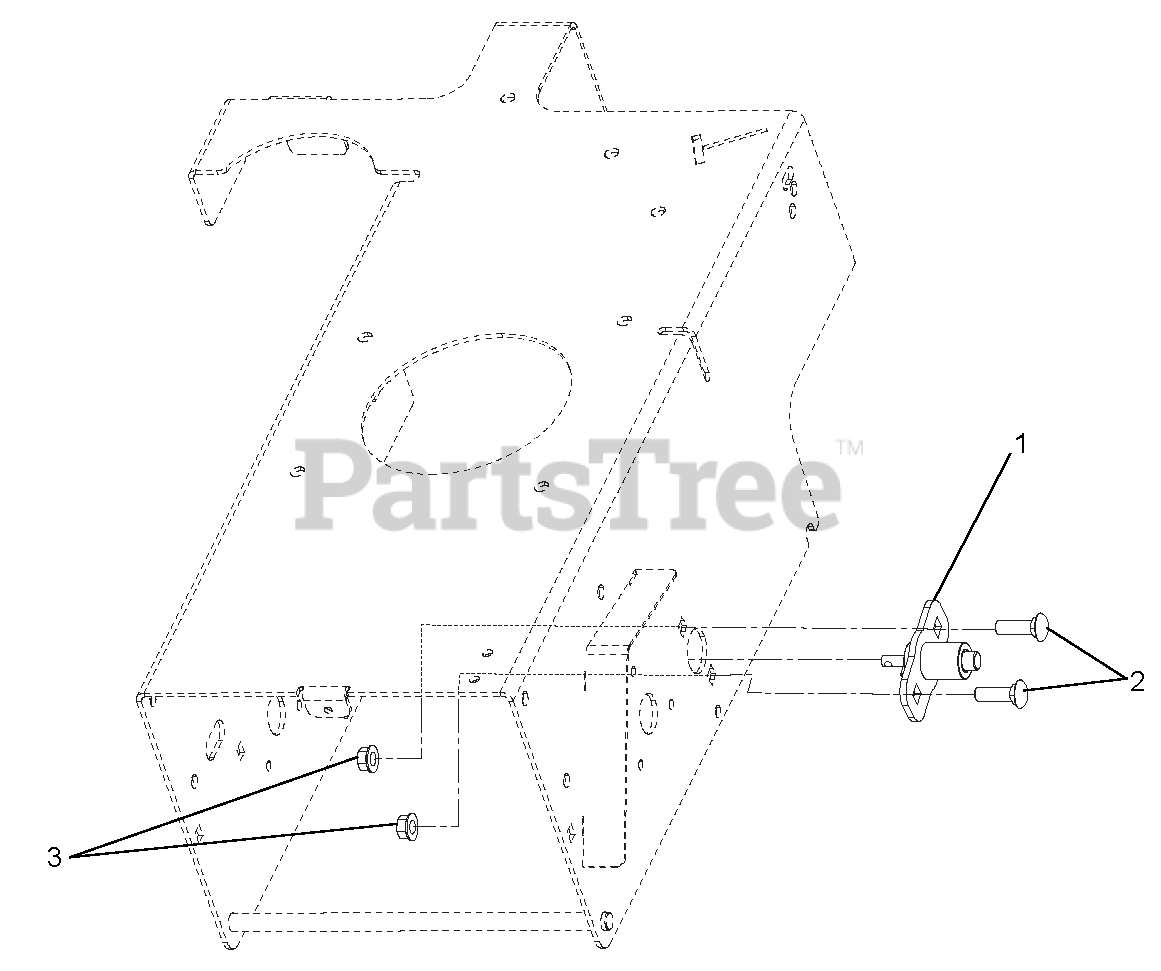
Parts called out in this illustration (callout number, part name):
1	KIT, WAW PIN BRAKE
2	@BLT-RDHDSQNK .38-16X1.25 G5YZ
3	@NUT-SPNLK-FLG .375-16 YWZC
